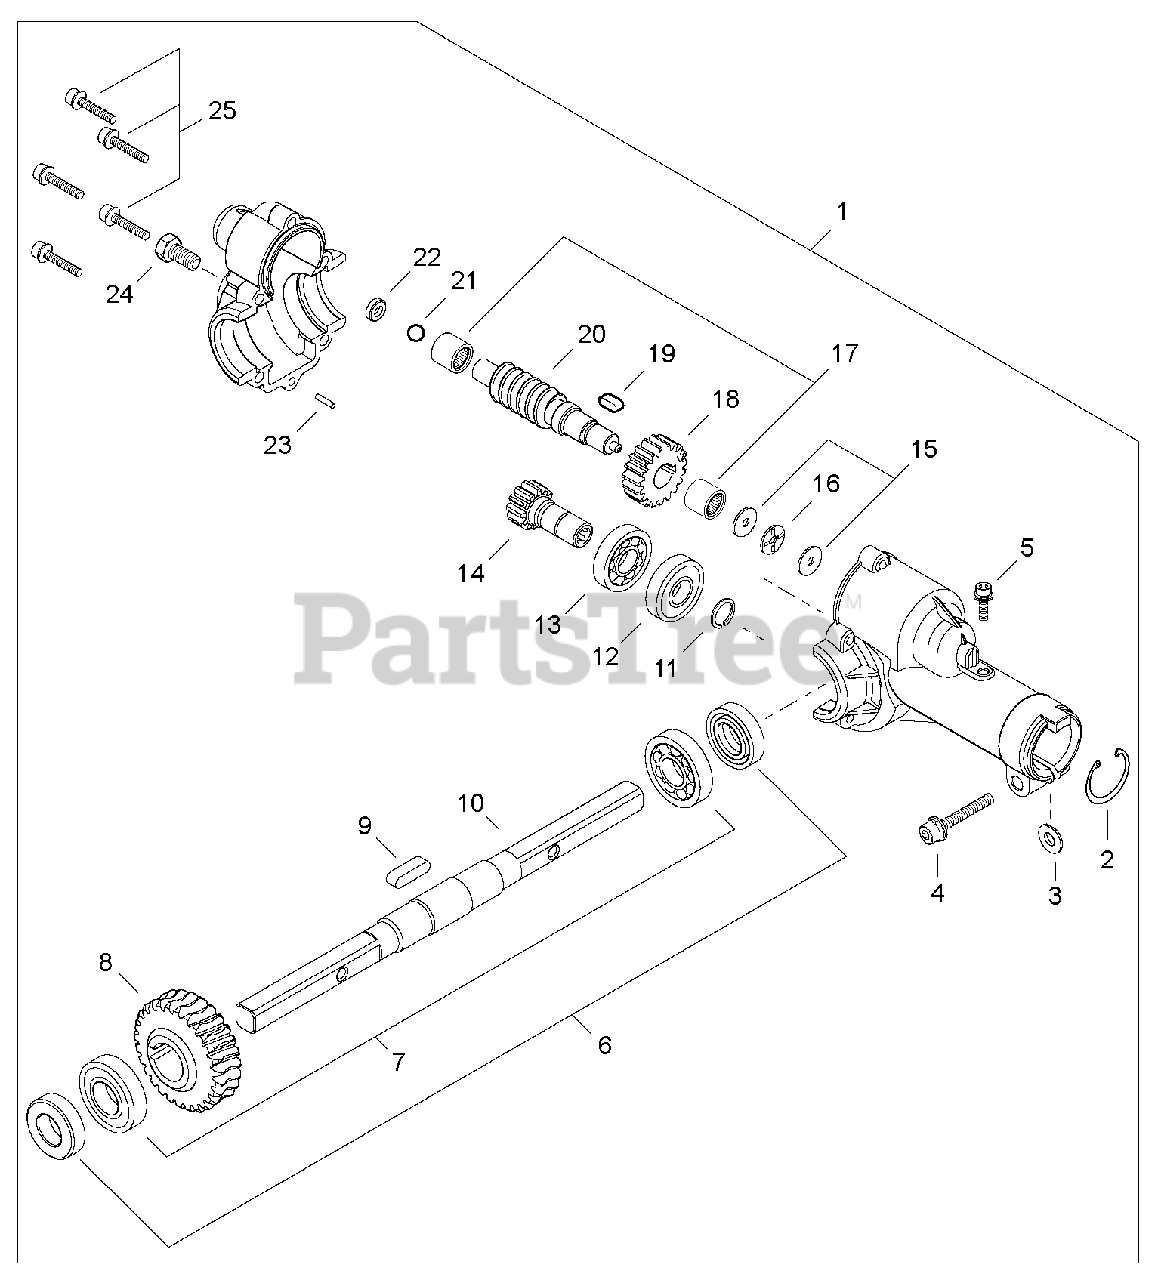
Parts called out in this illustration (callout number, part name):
1	GEAR CASE ASSY
2	RING, RETAINING - 24
4	SCREW - 6X30
5	SCREW - 5X12
6	SEAL, OIL - 17
7	BEARING, BALL - 6003
8	WHEEL, WORM
10	GEAR - SHAFT
11	RING, RETAINING - 12
12	BEARING, BALL - 6901
13	BEARING, BALL - 6901
14	GEAR - SPUR
16	BEARING, THRUST
17	BEARING, NEEDLE
18	GEAR - SPUR
20	GEAR - WORM
23	PIN - LOCATING
24	BOLT - 8X10
25	SCREW - 5X20
